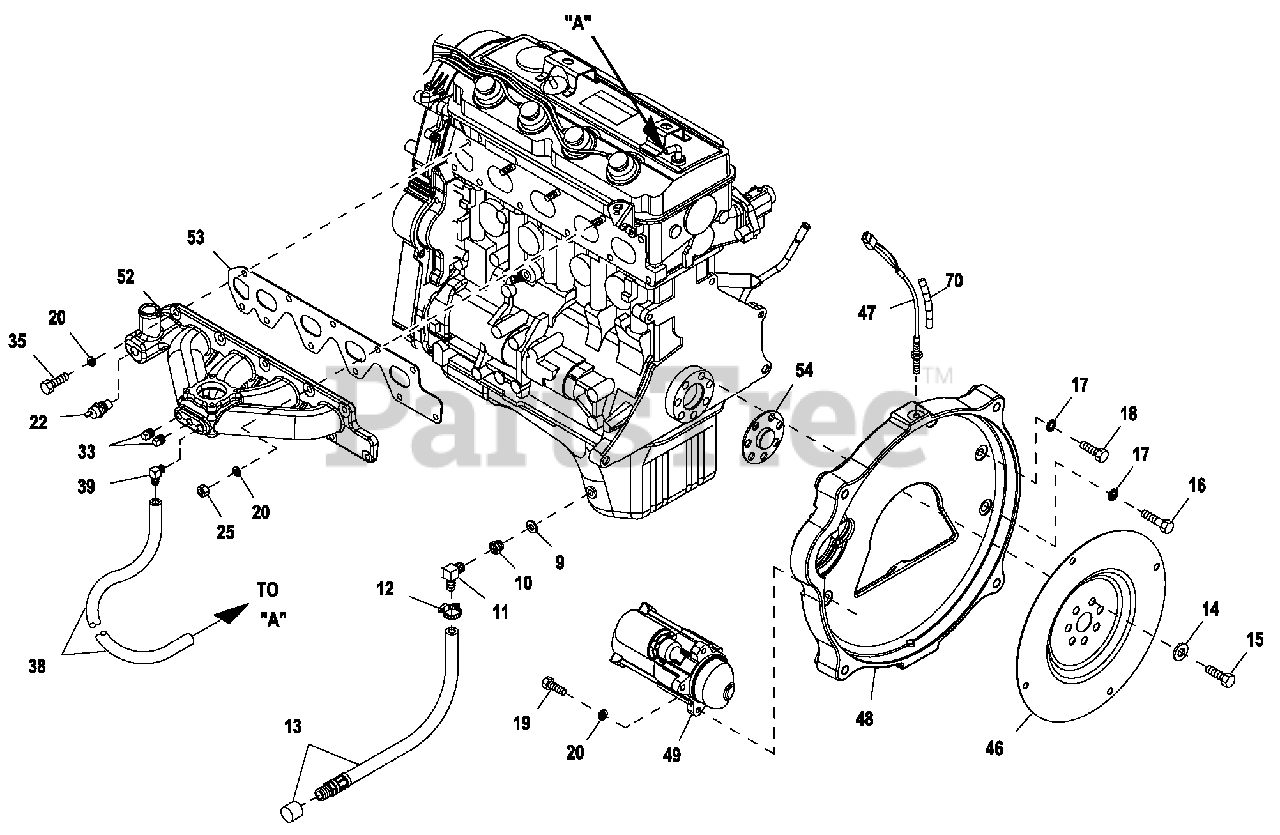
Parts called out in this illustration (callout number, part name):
9	ROTOR-2390-45KD1 CPL
10	ROTOR-2390-35KD1 CPL
11	ROTOR-2390-45KD1 CPL (G2)
12	ROTOR-2390-35KD1 CPL (G2)
13	ROTOR 25KW 3PH DIRECT 390 1800
14	ROTOR 25KW 1PH DIRECT 390 1800
15	SCREW HHC M12-1.25 X 20 G10.9
16	SCREW HHC M10-1.25X45 G8.8
17	WASHER SHAKEPROOF EXT 7/16 STL
18	STATOR-390 45K 2P 1PH DIRECT
19	STATOR-2390-35AD1 CPL
20	STATOR-2390-35KD1 CPL
22	STATOR-2390-35GD1 CPL
25	STATOR-2309-45KW 2P 3PH 208V
33	STATOR-2309-45-KD1 CPL
35	SCREW HHC M8-1.25X 25 G10.9
38	HOSE 3/8 ID SINGLE BRAID (15" LG)
39	BARBED EL 90 1/4 NPT X 3/8
46	FLEX PLATE 2 POLE 2.4L G2
47	ASSY MAGPICKUP(3/8-24 MALE)
48	ADAPTER ENGINE 2.4L MACHINE
49	STARTER MOTOR 12V
50	CAM SENSOR PIN ASSY
52	MANIFOLD INTAKE (MACHINED)
53	GASKET INTAKE MANIFOLD
54	SPACER 2.4L G2 FLEX PLATE
